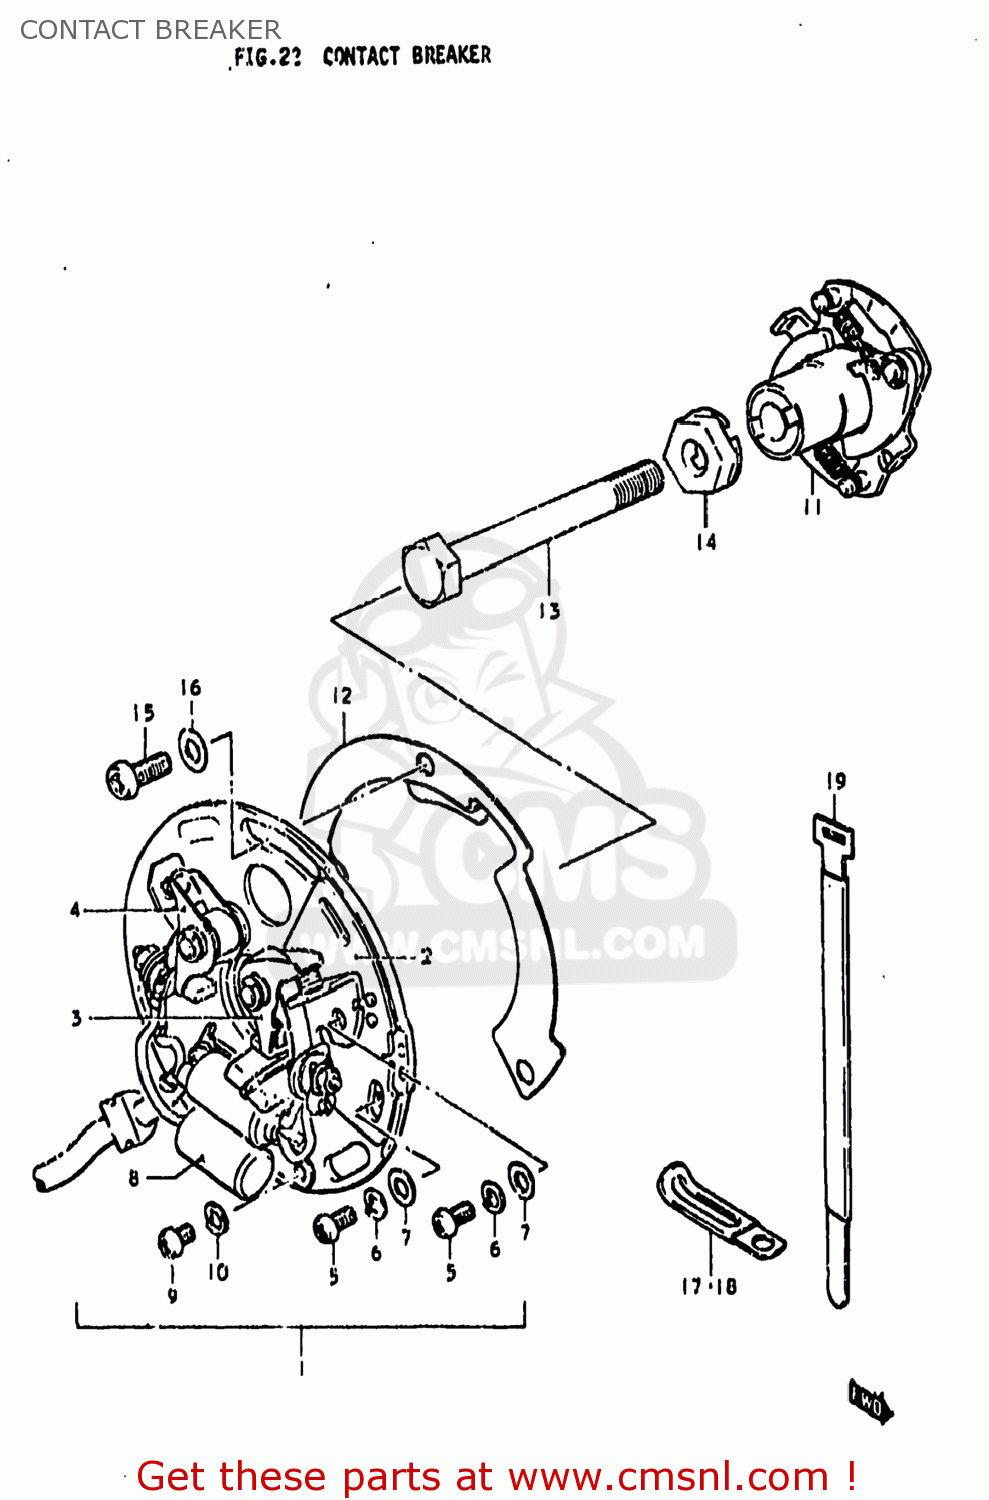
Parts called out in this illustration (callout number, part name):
1	BREAKER ASSEMBLY,CONTACT
2	PLATE,CONTACT POINT
3	POINT ASSY,R
4	POINT ASSY,L
5	SCREW(4X10)
6	LOCK WASHER
7	WASHER
8	CONDENSER
9	SCREW
10	LOCK WASHER
11	GOVERNOR ASSEMBLY
12	PLATE,IGNITION TIMING
13	BOLT
14	WASHER
15	SCREW(5X12)
16	WASHER 5MM
17	CLAMP L:35
18	CLAMP
19	CLAMP
